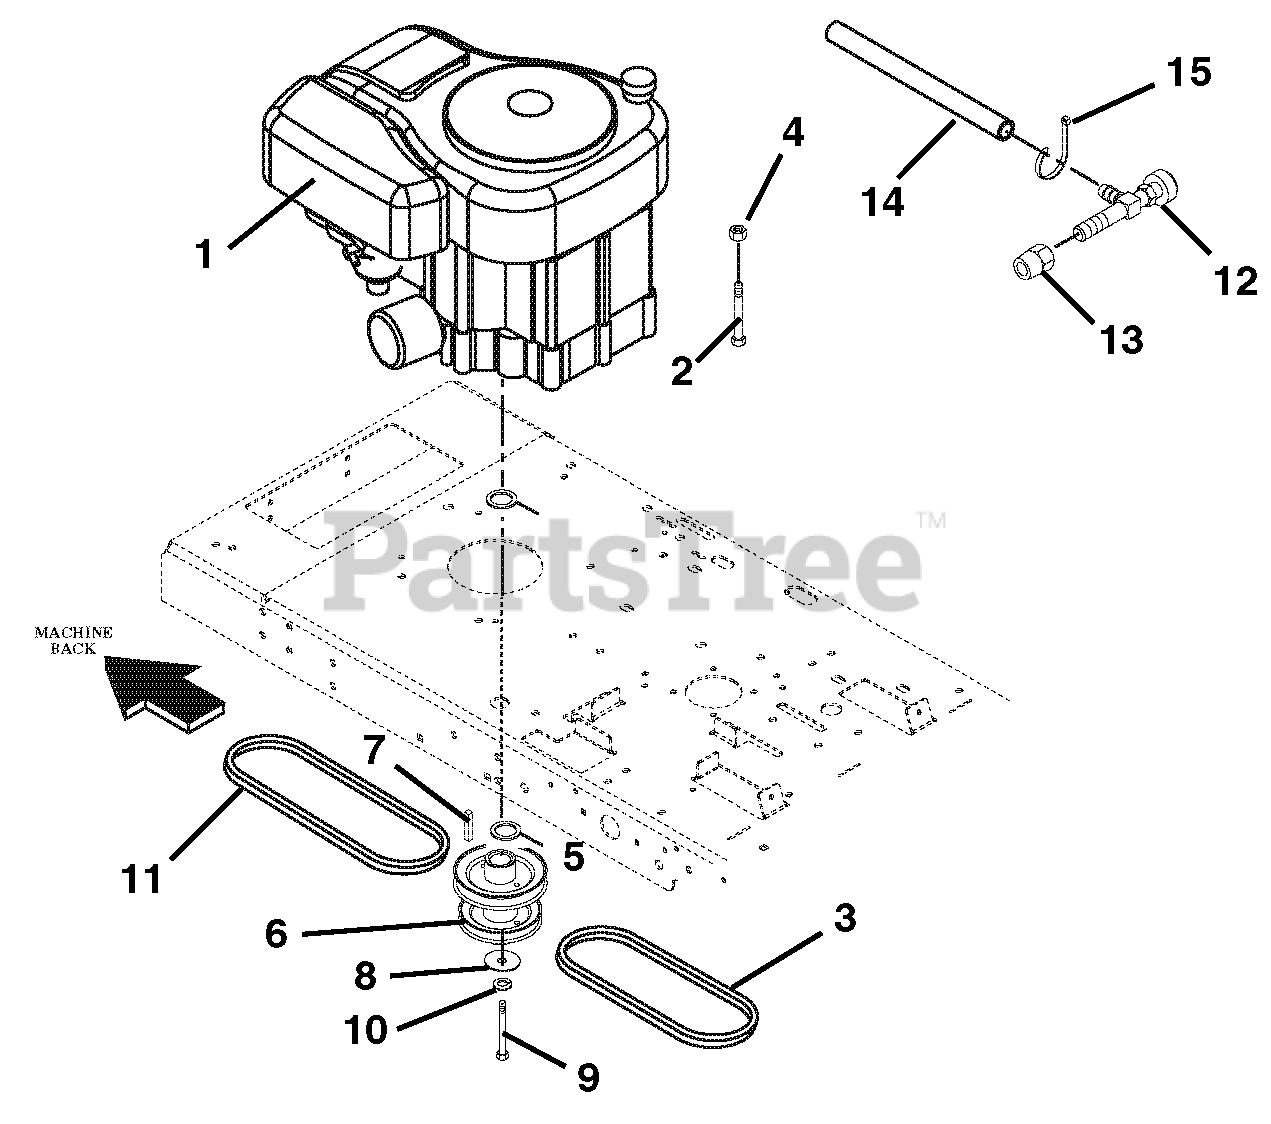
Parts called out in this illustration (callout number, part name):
1	Engine Group, Briggs & Stratton 15.5HP
2	Screw-Tapping .31-18 x 1.50 Hex Washer Head
3	Belt-5L x 47.1 Engine to Jackshaft
4	Nut-Locking-Top-Flange .31-18
6	Engine Sheave 4.50
7	Key-Square .25 x 2.50 x .25
8	Washer-Special .469 x 2.000 x .250
9	Bolt-Hex .44-20 x 3.00 Grade 5
10	Washer-Lock .44 x .109
11	V-Belt, Transmission Drive
12	Cock, Oil Drain
13	Adapter, Oil Drain
14	Tube, Oil Drain
15	Cable Tie
